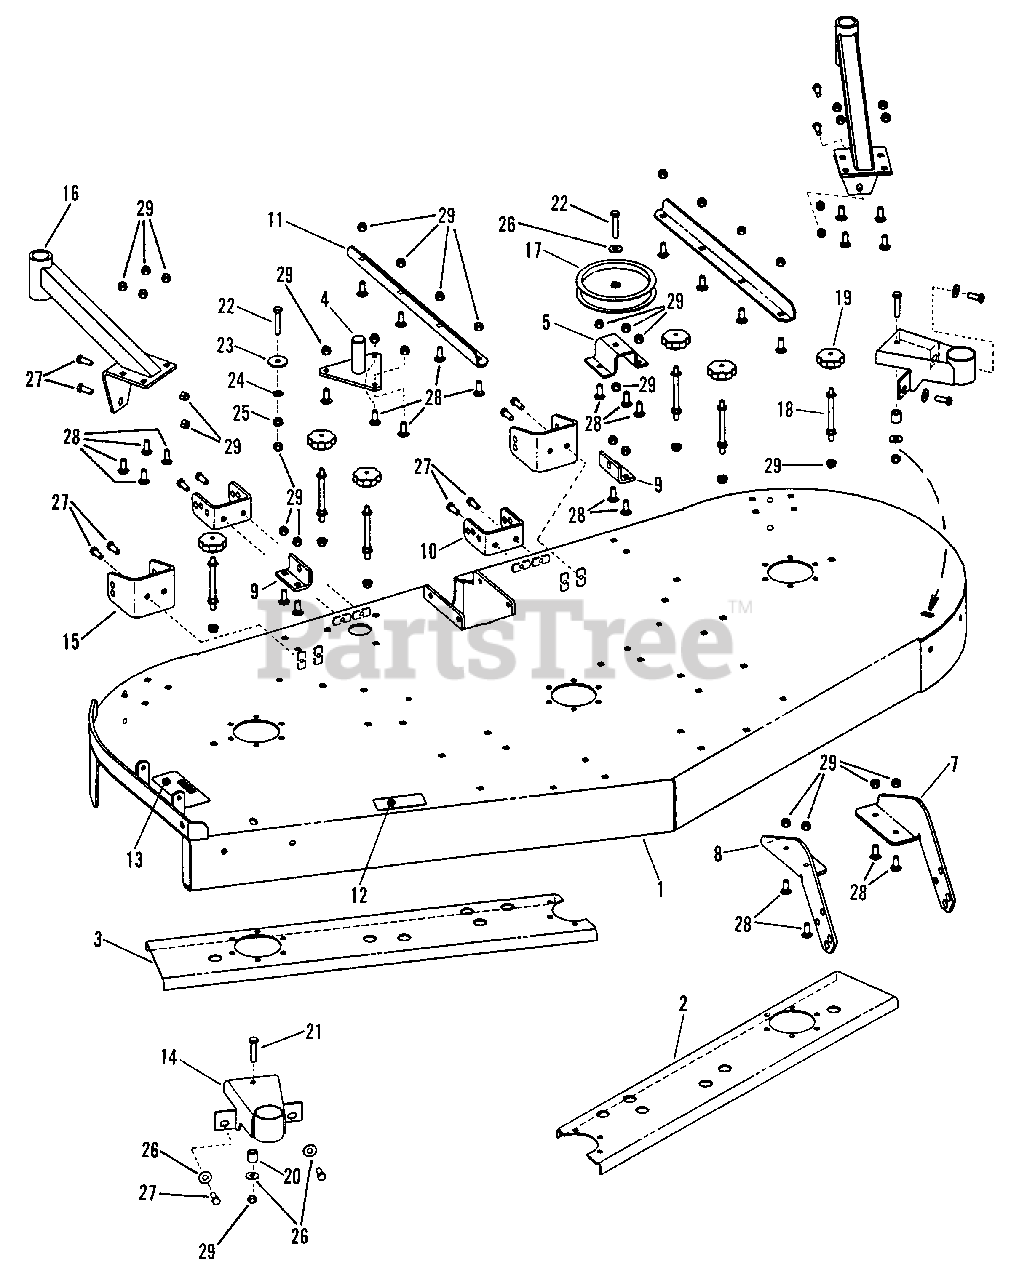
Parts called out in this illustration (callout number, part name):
1	WELDMENT, 73" Deck
2	CHANNEL, L.H. Deck Stiffener
3	CHANNEL, R.H. Deck Stiffener
4	WELDMENT, Idler Pivot
5	STAND, Fixed Idler
7	ROLLER MOUNT, L.H.
8	ROLLER MOUNT, R.H.
9	HANGER BRACKET, Rear Deck Lift
10	BRACKET, Rear Deck Hanger
11	STIFFENER, Deck
12	DECAL, 73" Deck
13	DECAL, Warning
14	WELDMENT, Gage Wheel
15	BRACKET, Gage Wheel
16	WELDMENT, Caster Support
17	PULLEY, Idler 5-1/2" O.D.
18	STANDOFF, 3-1/2"
19	KNOB, 5/16-18
20	SPACER
21	SCREW, 3/8-16 x 1-3/4" Hex Head Cap, Grade 5
22	BOLT, 3/8-16 X 2, GD5, CZ
23	WASHER, .406 I.D. x 1-1/2" O.D. Flat
24	RETAINER, 3/8" Bolt
25	NUT, 3/8-16 HEX SERRATED FLANGE
26	WASHER, 3/8" USS
27	BOLT, 3/8-16 X 1" GD5 CZ
28	BOLT, 3/8-16 x 1" square Neck Carriage, Grade 5
29	NUT, 3/8-16 HEX NYLON LOCK
